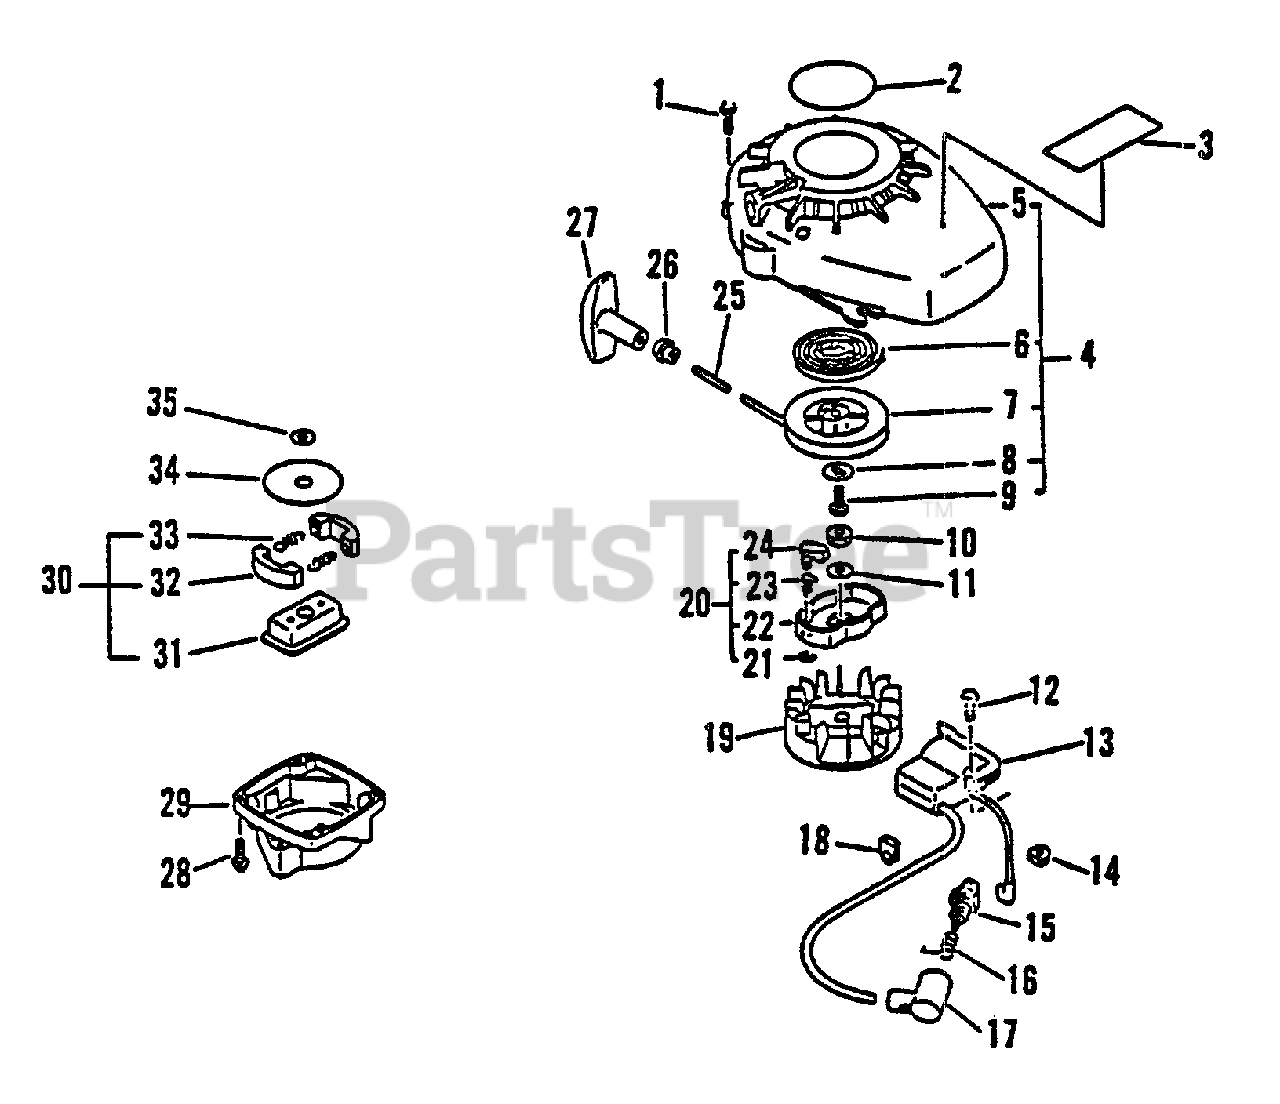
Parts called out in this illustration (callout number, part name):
1	SCREW 4×16
3	LABEL, LHD-1700
4	STARTER ASSY
5	CASE, STARTER
6	SPRING, RECOIL
7	REEL, ROPE
8	WASHER
10	NUT 8×1.25
11	WASHER 8.5×16×1.2
12	SCREW 4×22
13	COIL, IGNITION
15	SPARK PLUG - BPM6A
16	TERMINAL, SPARK PLUG
17	CAP, SPARK PLUG
19	FLYWHEEL
20	STARTER PAWL ASSY
21	E-RING 4
22	CATCHER, PAWL
23	SPRING, RETURN
24	PAWL, STARTER
26	GUIDE, ROPE
27	GRIP, STARTER
28	BOLT 4×16
29	HOUSING, CLUTCH
30	CLUTCH ASSY
31	BOSS, CLUTCH
32	SHOE, CLUTCH
33	SPRING, CLUTCH
34	PLATE, CLUTCH
35	WASHER, CLUTCH
